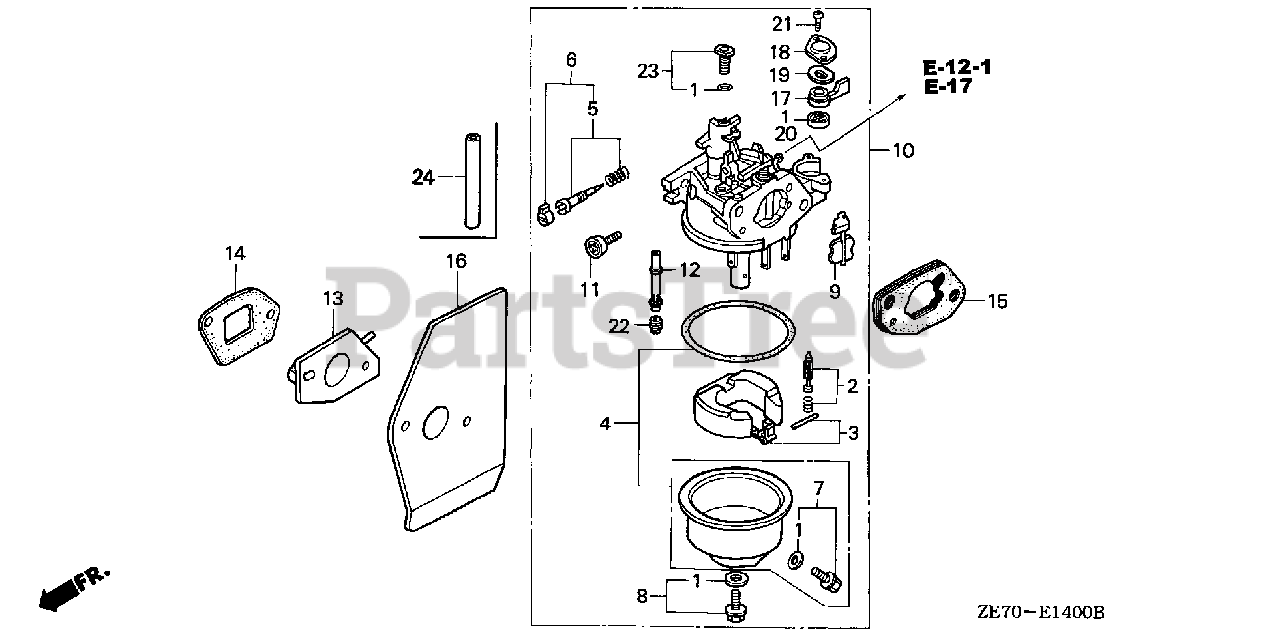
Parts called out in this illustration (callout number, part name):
1	GASKET SET (CARBURETOR NO.)
2	VALVE SET, FLOAT
4	CHAMBER SET, FLOAT
6	SCREW SET, PILOT (CARBURETOR NO.)
7	SCREW SET, DRAIN
8	SCREW SET
9	CHOKE SET (CARBURETOR NO.)
10	CARBURETOR ASSY. (BE66A B) (NA USE ALT:16100-ZE7-055)
11	SCREW, THROTTLE STOP
12	NOZZLE, MAIN (CARBURETOR NO.)
13	INSULATOR, CARBURETOR
14	GASKET, INSULATOR
15	SPACER, CARBURETOR
16	GASKET, CARBURETOR
17	LEVER, VALVE
17	LEVER, PETCOCK (CARBURETOR NO.)
18	PLATE, LEVER SETTING (CARBURETOR NO.)
19	SPRING, PETCOCK LEVER
20	GASKET, PETCOCK (CARBURETOR NO.)
21	SCREW, PAN (3X6)
21	SCREW, PAN (3X8)
22	JET, MAIN (#62) Use from Engine SN BE40A G.
22	JET, MAIN (#65) (CARBURETOR NO.)
22	JET, MAIN (#68) (CARBURETOR NO.)
23	JET SET, PILOT (#40) (CARBURETOR NO.)
